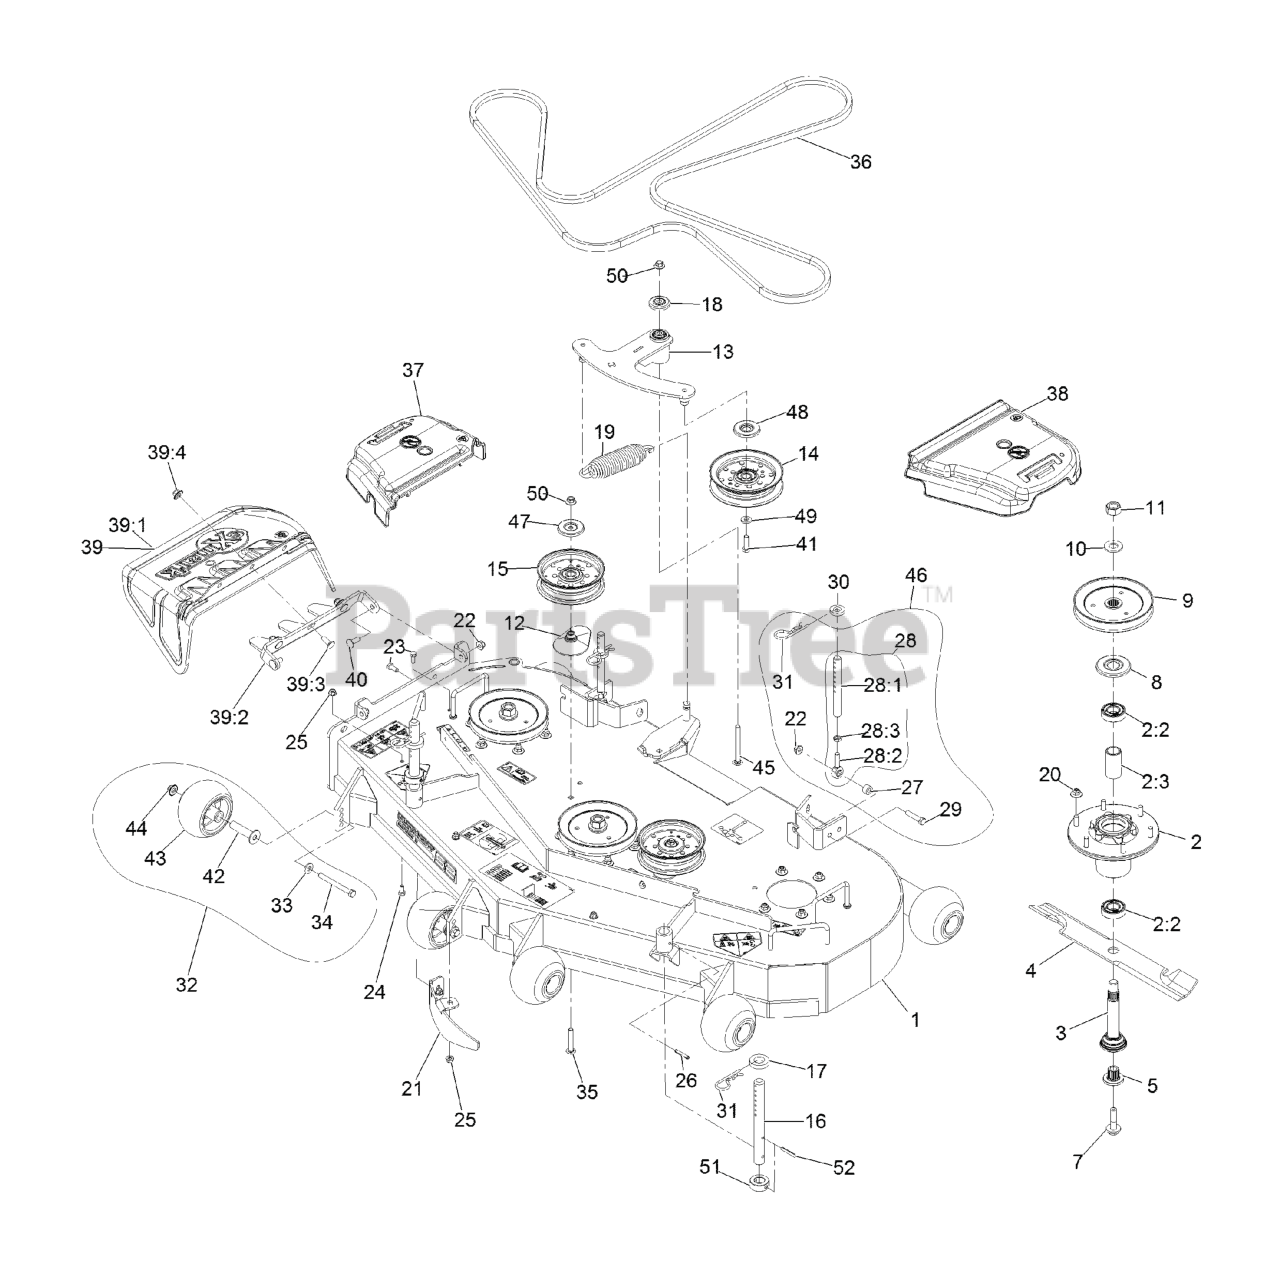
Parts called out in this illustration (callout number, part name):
1	ASM, DECK W/ DECALS, 52"
2	ASM-CUTTER HSG WITH BEARINGS
2:2	BEARING-BALL
2:3	SPACER-BEARING
3	ASM-SPINDLE AND SEAL
5	BUSHING,SPLINED
7	SCREW,SEMS 1/2-20 X 2.19
8	GUARD,BEARING TOP .989
9	SHEAVE,BLADE DRIVE 6.50
11	NUT-HEX
12	SPACER-PULLEY
13	ASM, DECK IDLER
14	IDLER-PULLEY, FLAT
15	IDLER-PULLEY, FLAT 5.00X1
16	Rod, Deck Support
17	SPACER-DECK SUPPORT
18	GUARD-TOP
19	SPRING-EXTENSION
20	Nut-Nyloc 3/8-16 Flg
21	BAFFLE, DOGLEG
22	NUT-HF, NI
23	SCREW-HH
24	SCREW-HH
25	NUT-HF, NI
28:1	LINK,SUPPORT
28:2	BALLJOINT
28:3	NUT-HJ
29	SCREW-HH
31	PIN,HAIR COTTER
32	KIT, ANTI-SCALP ROLLER
33	WASHER-BELLEVILLE
34	SCREW-HH 3/8-16 X 3 3/4 GR 8
35	BOLT-CARR, SHORT NECK
36	BELT, DECK
37	COVER-BELT, RH
38	COVER-BELT, LH
39	ASM, DISCHARGE CHUTE
39:1	CHUTE,DISCHARGE
39:2	BRACKET, DISCHARGE CHUTE
39:3	SCREW-CARR
39:4	Nut-Nyloc 3/8-16 Flg
40	SCREW-CARR
41	SCREW-HH
42	AXLE, ROLLER
43	ROLLER-SCALP, ANTI
44	Nut-Nyloc 3/8-16 Flg
45	SCREW-CARR
46	KIT,SUPPORT LINK W/PIN
47	SHIELD-DUST
48	SHIELD-GUARD, DUST
51	Collar, Deck Height Pin
52	PIN-ROLL
